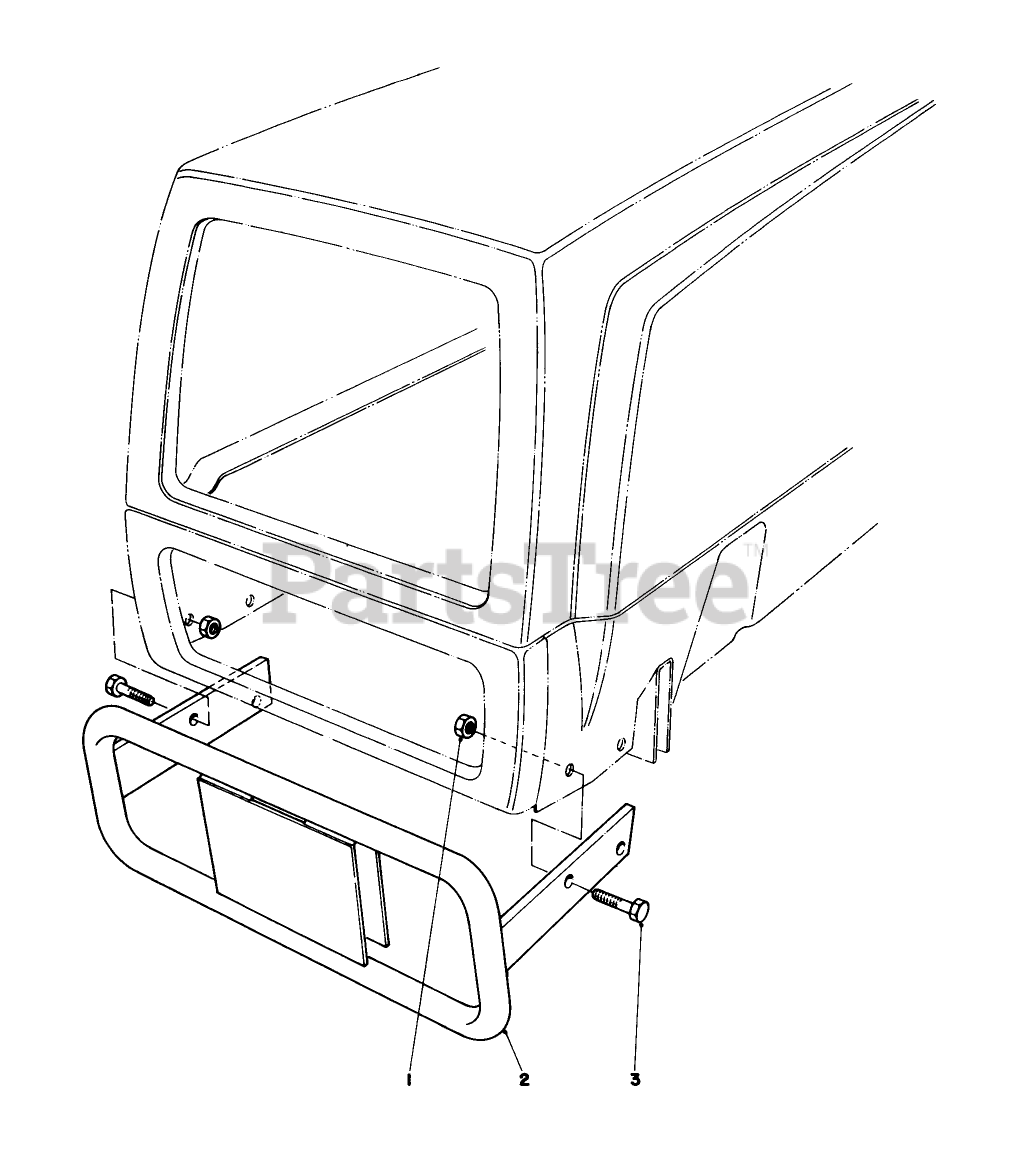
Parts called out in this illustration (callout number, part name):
1	NUT-LOCK, CONE
2	Bumper W.A.
3	SCREW-HH
